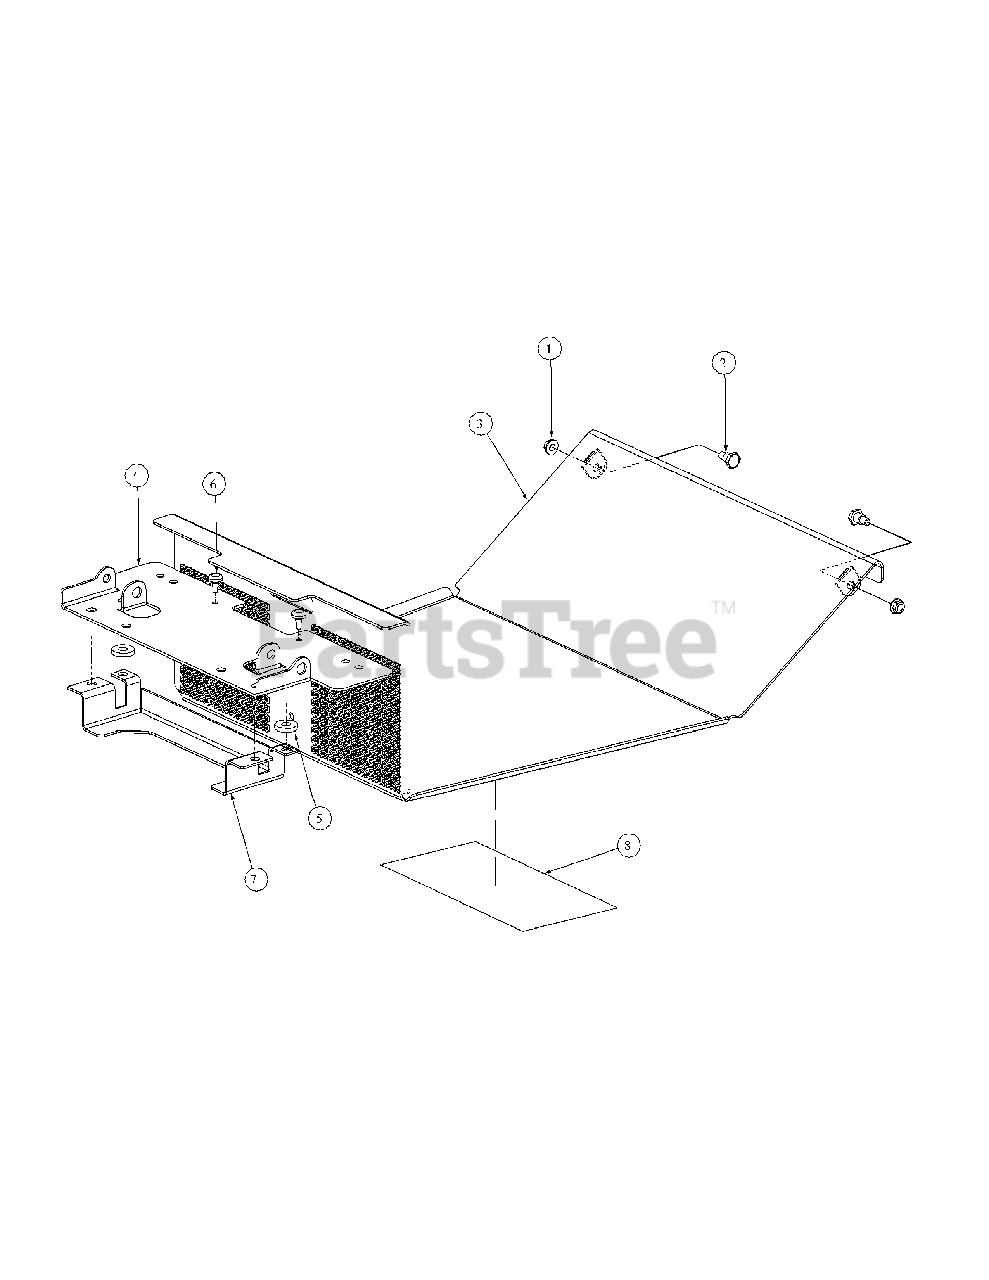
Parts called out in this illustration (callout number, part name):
1	Lock Nut, Hex Flange 5/16-18
2	Shoulder Screw, .435 x .350, 5/16-18
3	Floor Assembly Panel
4	Panel Seat
5	Washer
6	Rubber Bumper, .62 OD x .22 Thick
7	Support, Seat Bracket
8	Label, Belt Routing and Lubrication
